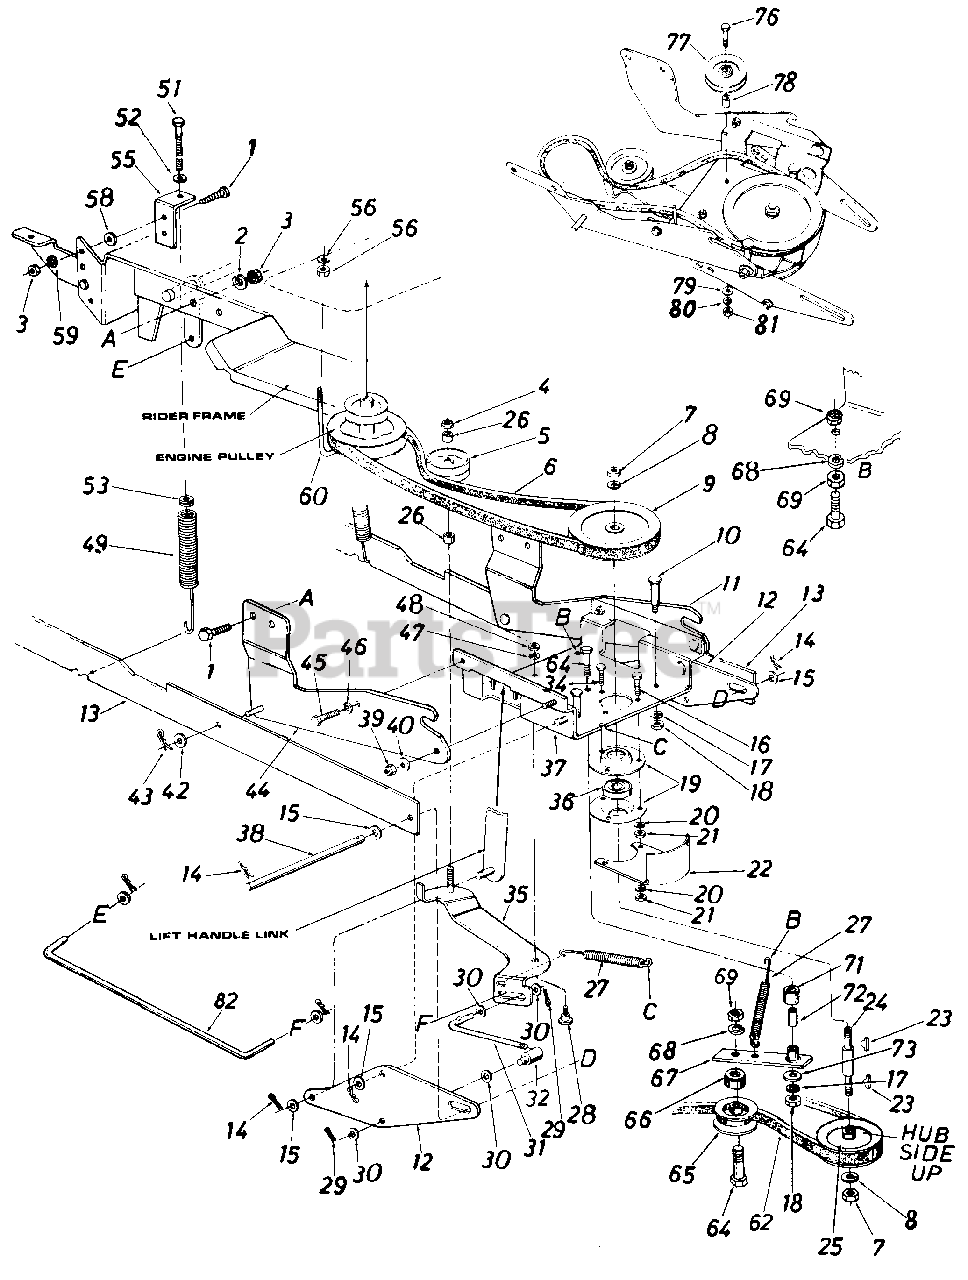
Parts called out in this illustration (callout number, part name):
1	Hex Bolt 1/4-28 x .75" Lg Grade 5
2	L.-Wash. 1/4" I.D.
3	Hex Nut 1/4-28 Thd.
4	Hex Cent. L-Nut 3/8-16 Thd.
5	Idler Pulley
6	"V"-Belt 1/2 x 49" Lg.
7	Hex Jam Nut 5/8-11 Thd.
8	L-Wash. 5/8" I.D.
9	6.50" O.D. x 5/8 Pulley
10	ShouIder Bolt
11	Channel Supporting Brkt.-R.H.
12	Linkage Brkt.
13	Linkage Arm Ass'y.
14	Intern. Cotter Pin .50 Dia.
15	Fl.-Wash.
16	Hex Bolt 5/16 x 1.25"Lg.
17	L.-Wash. 3/8" I.D.
18	Hex Jam Nut 3/8-16 Thd.
19	Bearing Housing
20	L.-Wash. 5/16" I.D.
21	Hex Nut 5/16-18 Thd.
24	Pulley Spindle
25	5/8 Pulley-6.28 I.D. x 5.56 O.D.
26	Spacer .383 I.D. x .503 O.D. x .562 Lg.
27	Extension Spring .54 O.D. x 5.25"
28	Shoulder Bolt
29	Cotter Pin 3/32" Dia. x 1.0"
30	Fl.-Wash.
31	Control Rod
32	Ferrule
34	Hex Sems Scr. 5/16-18 x .75" Lg.
35	Clutch Idler Brkt. Ass'y.
36	Ball Bearing
37	Channel Ass'y.
38	Lift Handle Shaft
39	Hex Jam Nut 3/8-16 Thd.
40	L.-Wash. 3/8" I.D.
42	Fl.-Wash.
43	Intern. Cotter Pin .50" Dia.
44	Channel Supporting Brkt.-L.H.
45	Hex Bolt 3/8-16 x x 1.0"Lg.
46	L.-Wash: 3/8" I.D.
47	L.-Wash. 5/16" I.D.
48	Hex Nut 5/16-18 Thd.
49	Helper Spring
51	Hex Scr. 5/16-18 x 2.0" Lg. Special
52	Bell Wash. .345 I.D. x .88 O.D. x .06
53	Spring Insert
58	Fl.-Wash. .264" I.D.
59	L.-Wash. 1/4" I.D.
60	J-Bolt 5/16-18 Thd.
62	"V"-Belt 1/2 "A" x .89" Lg.
64	Hex Bolt 3/8-16 x 2.0" Lg.
65	Idler Pulley
66	Spacer .385 I.D. x .503 0.D. x.562" Lg.
67	Idler Arm Ass'y.
68	L.-Wash. 3/8" I.D.
69	Hex Jam Nut 3/8-16 Thd.
71	Spacer .380" I.D. x 1.0" O.D.
72	Spacer .3775 I.D. x .60 O.D. x 8.3 Lg.
73	Fl.-Wash. 3/8 I.D. x 1" O.D. x 1.27
76	Hex Bolt 3/8-16 x 2.5" Lg. (Grade 5)
77	Idler Pulley .38 I.D. x 3.06 O.D.
78	Spacer .385 I.D. x .630 O.D. x .76 Lg.
79	Fl.-Wash. .39 I.D. x 1-3/4 O.D. x 3/16"
80	L-Wash. 3/8" I.D.
81	Hex Nut 3/8-16 Thd.
